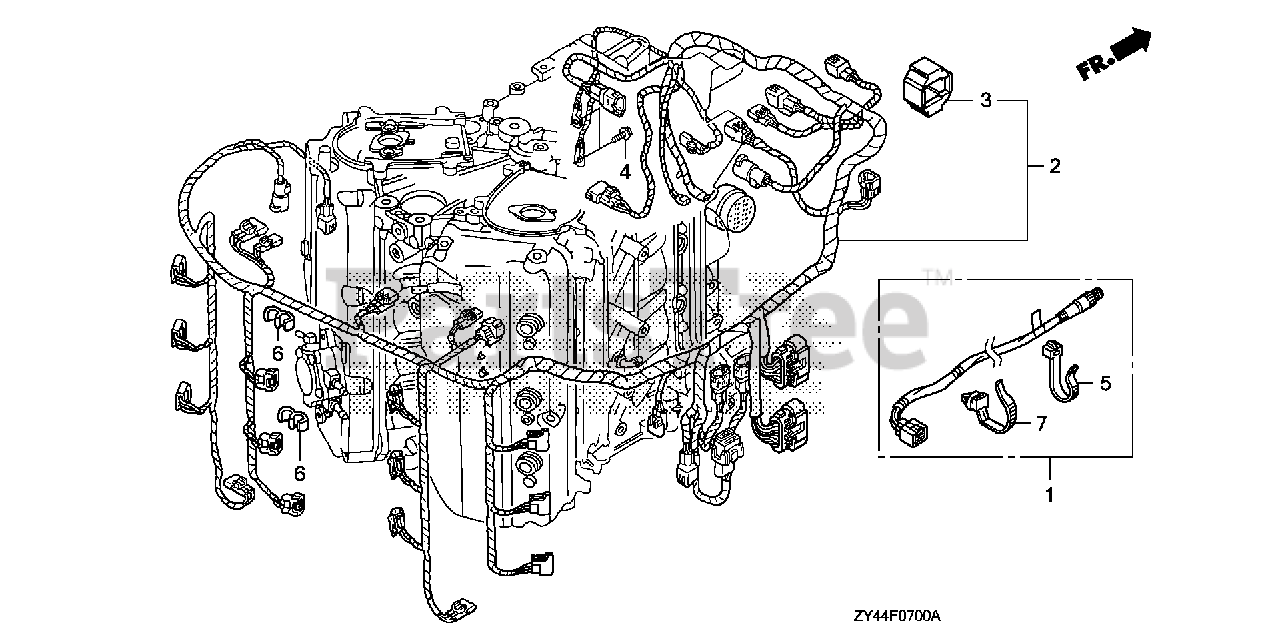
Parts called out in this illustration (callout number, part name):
1	KIT, CABLE (6FT) (NMEA)
2	WIRE HARNESS ASSY., MAIN
3	SUSPENSION, CONNECTOR
4	BOLT, FLANGE (6X12)
5	TIE, CABLE
6	CLIP A, HARNESS
7	CLIP, HARNESS BAND (155.3MM) (BLACK)
